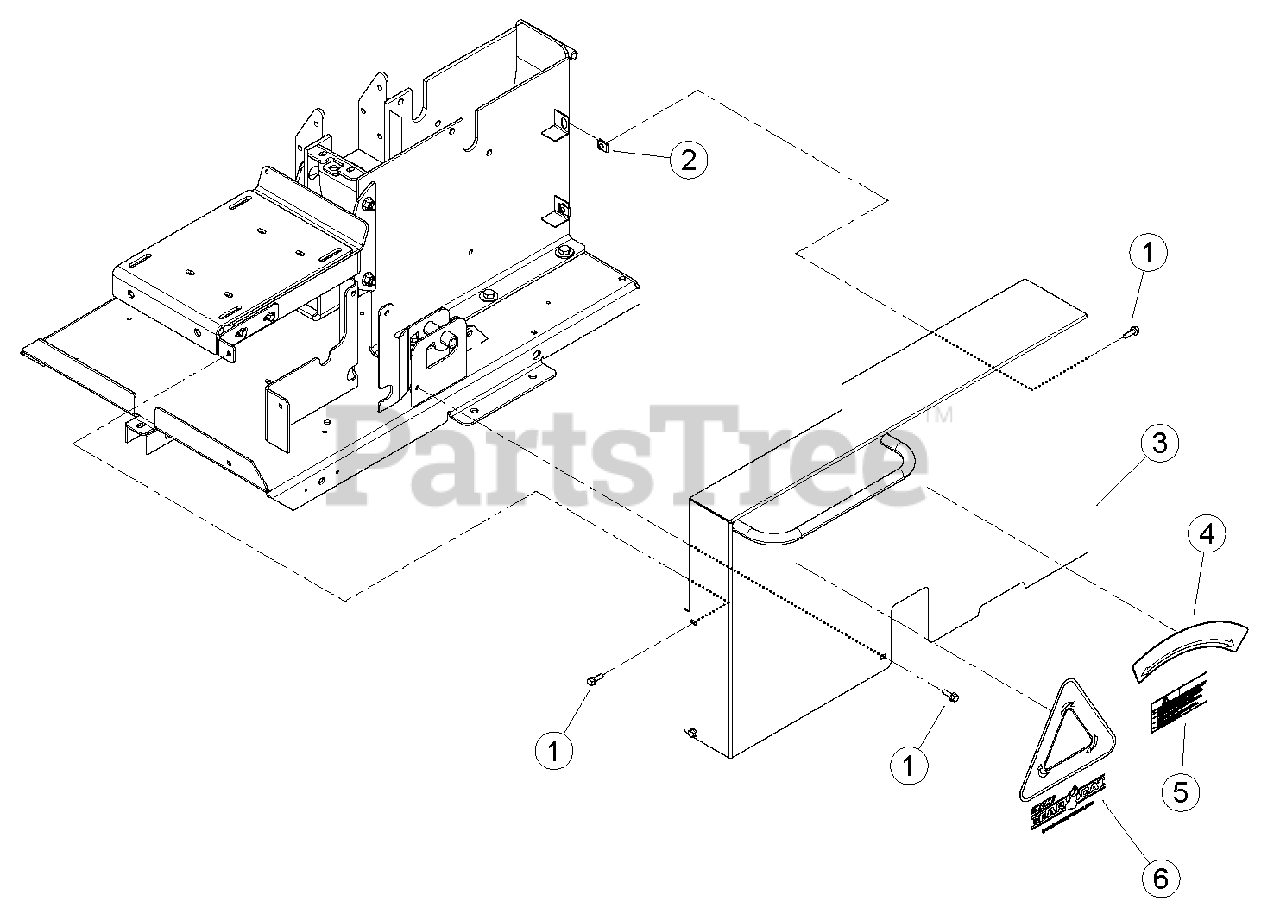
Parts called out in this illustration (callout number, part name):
1	BOLT, 5/16 X 1 FLANGE NC
2	NUT, 5/16"-18 TINNERMAN U-TYPE
3	ASSEMBLY, SHIELD WITH DECALS (REPLACED AND SUPERSEDED PN 76973-00)
4	DECAL, START/ENGAGE
5	DECAL, MUTILINGUAL MANUAL
6	DECAL, CHIP IT LARGE
